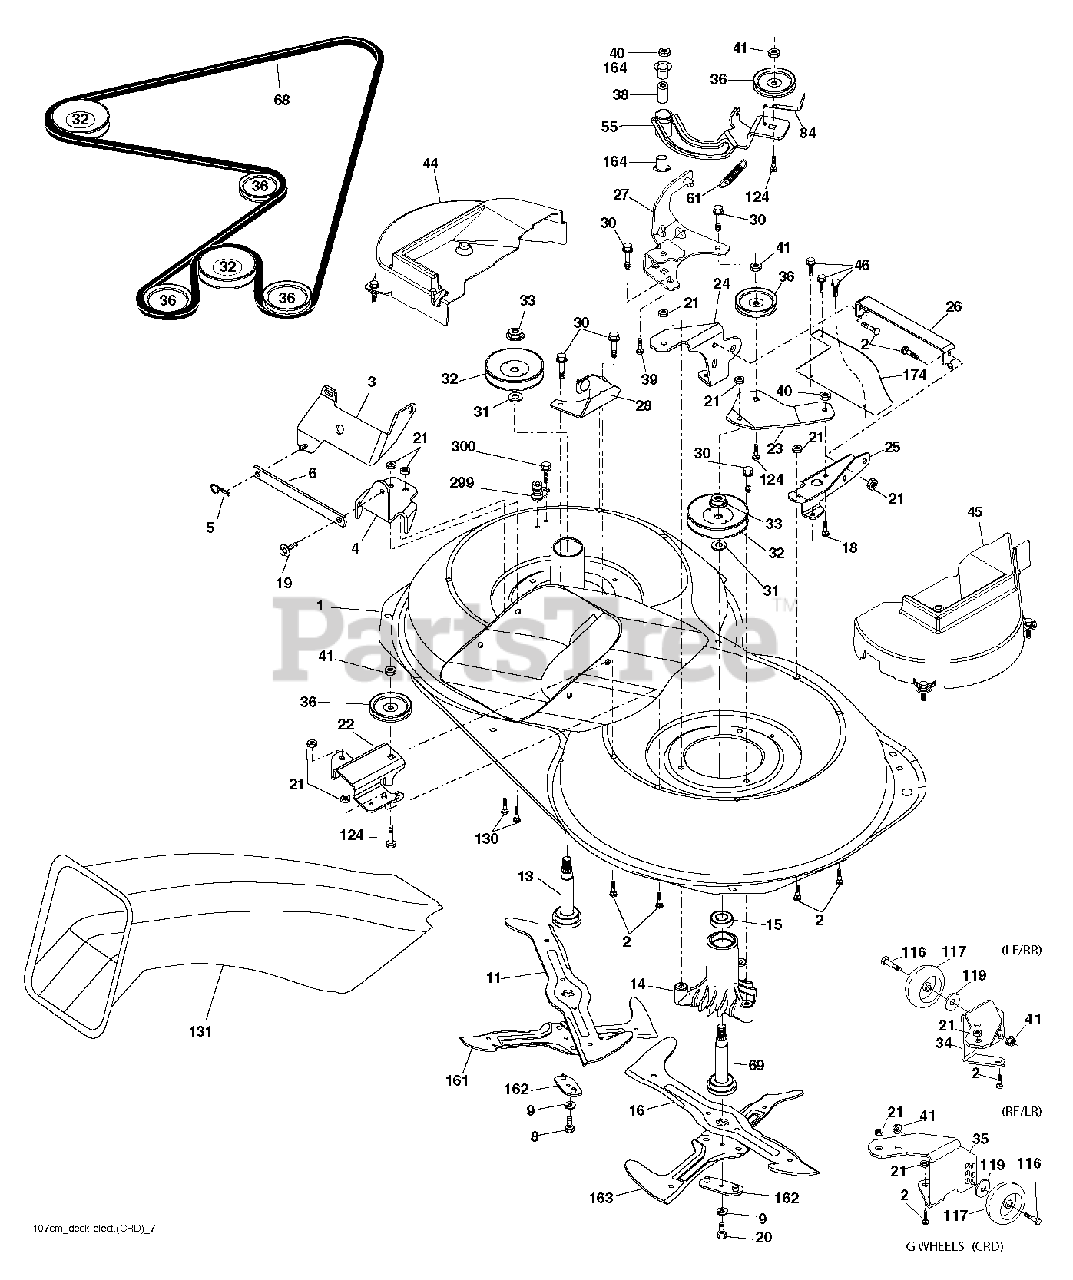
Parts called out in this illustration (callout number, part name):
2	BOLT
3	BRACKET.ASM.BAR.SWAY.CHASS
5	RETAINER-SPRNG RB
6	BAR SWAY
9	LOCKWASHER
11	BLADE.3N1.LH.CRD
13	SHAFT ASM VENT
14	HSG MANDREL
16	BLADE.3N1.RH.CRD
19	BOLT SHD 5/16-18
21	LOCKNUT
22	BRACKET
23	BRACKET
27	BRACKET
30	SCREW, WASHER HEAD
31	WASHER.SPACER.MANDREL
33	NUT.FLANGE.LOCK.TOP
36	PULLEY.IDLER.4.25
40	LOCKNUT
41	NUT LOCK FLG 3/8-16 UNC
46	SCREW.1/4-20X5/8
55	ARM IDLER
68	HEX-BELT 107 MOWER
69	SHAFT.ASM.W/LWR.BRG.RH.THREAD
84	KEEPER, BELT IDLER
116	BOLT.SHOULDER.3/8-16X3-5/8
117	WHEEL. GUAGE RALLY
124	BOLT.3/8-16X1.50
131	CHUTE BAGGER
164	BRNG T
299	PORT.WASHOUT
